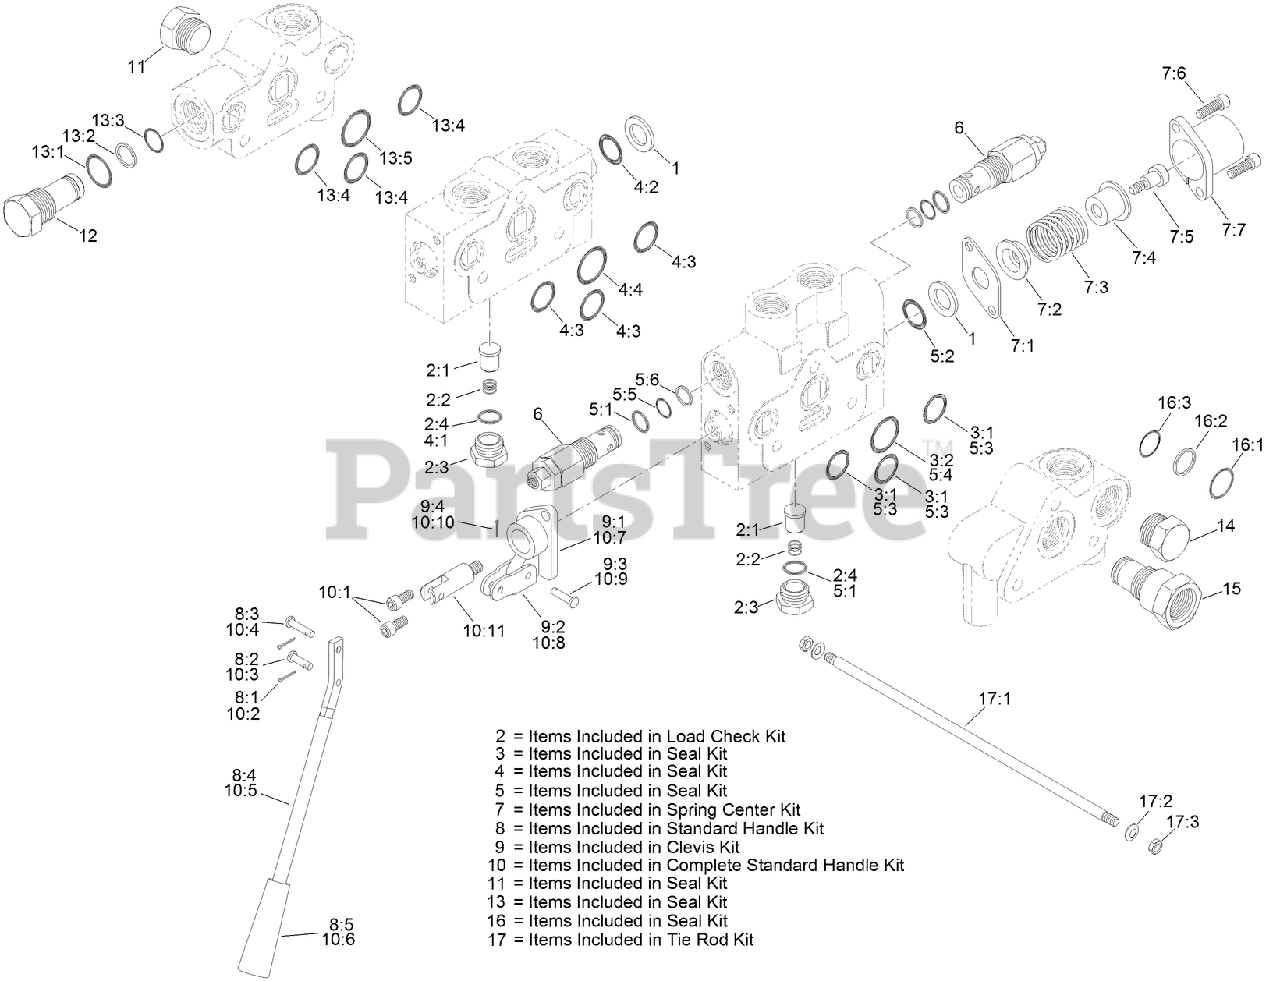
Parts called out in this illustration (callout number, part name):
1	WASHER-BACK UP, SPOOL
2	LOAD CHECK KIT
2:1	POPPET-CHECK, LOAD
2:2	SPRING-CHECK, LOAD
2:3	PLUG-CHECK, LOAD
2:4	O-RING
3	REPLACEMENT SEAL KIT
3:1	O-RING
3:2	O-RING
4	SVW REPLACEMENT SEAL KIT
4:1	O-RING
4:2	O-RING
4:3	O-RING
4:4	O-RING
5	SVH REPLACEMENT SEAL KIT
5:1	O-RING
5:2	O-RING
5:3	O-RING
5:4	O-RING
5:5	Washer-Backup
5:6	O-RING
6	CARTRIDGE-RELIEF
7	SPRING CENTER KIT
7:1	PLATE-RETAINER
7:2	CUP-STOP, INNER
7:3	Spring-Centering
7:4	CUP-STOP, OUTER
7:5	ADAPTER-SPOOL
7:6	Screw-Cap
7:7	Cap-End
8	STANDARD HANDLE KIT
8:1	Pin-Cotter
8:2	Pin-Clevis
8:3	Pin-Clevis
8:4	Handle
9	CLEVIS KIT
9:1	Clevis
9:2	Link
9:3	Pin-Clevis
9:4	Pin-Cotter
10	STANDARD HANDLE KIT
10:1	Screw-Cap
10:2	Pin-Cotter
10:3	Pin-Clevis
10:4	Pin-Clevis
10:5	Handle
10:7	Clevis
10:8	Link
10:9	Pin-Clevis
10:10	Pin-Cotter
10:11	ADAPTER-SPOOL
11	PLUG-PORT
12	PLUG-NO RELIEF
13	REPLACEMENT INLET SEAL KIT
13:1	O-RING
13:2	Washer-Back Up
13:3	O-RING
13:4	O-RING
13:5	O-RING
15	CARTRIDGE-BEYOND, POWER
16	OUTLET SECTION SEAL KIT
16:1	O-RING
16:2	Washer-Back Up
16:3	O-RING
17	TIE ROD KIT (4 SECTION)
17:1	Rod-Tie
17:2	Washer-Lock
17:3	NUT
